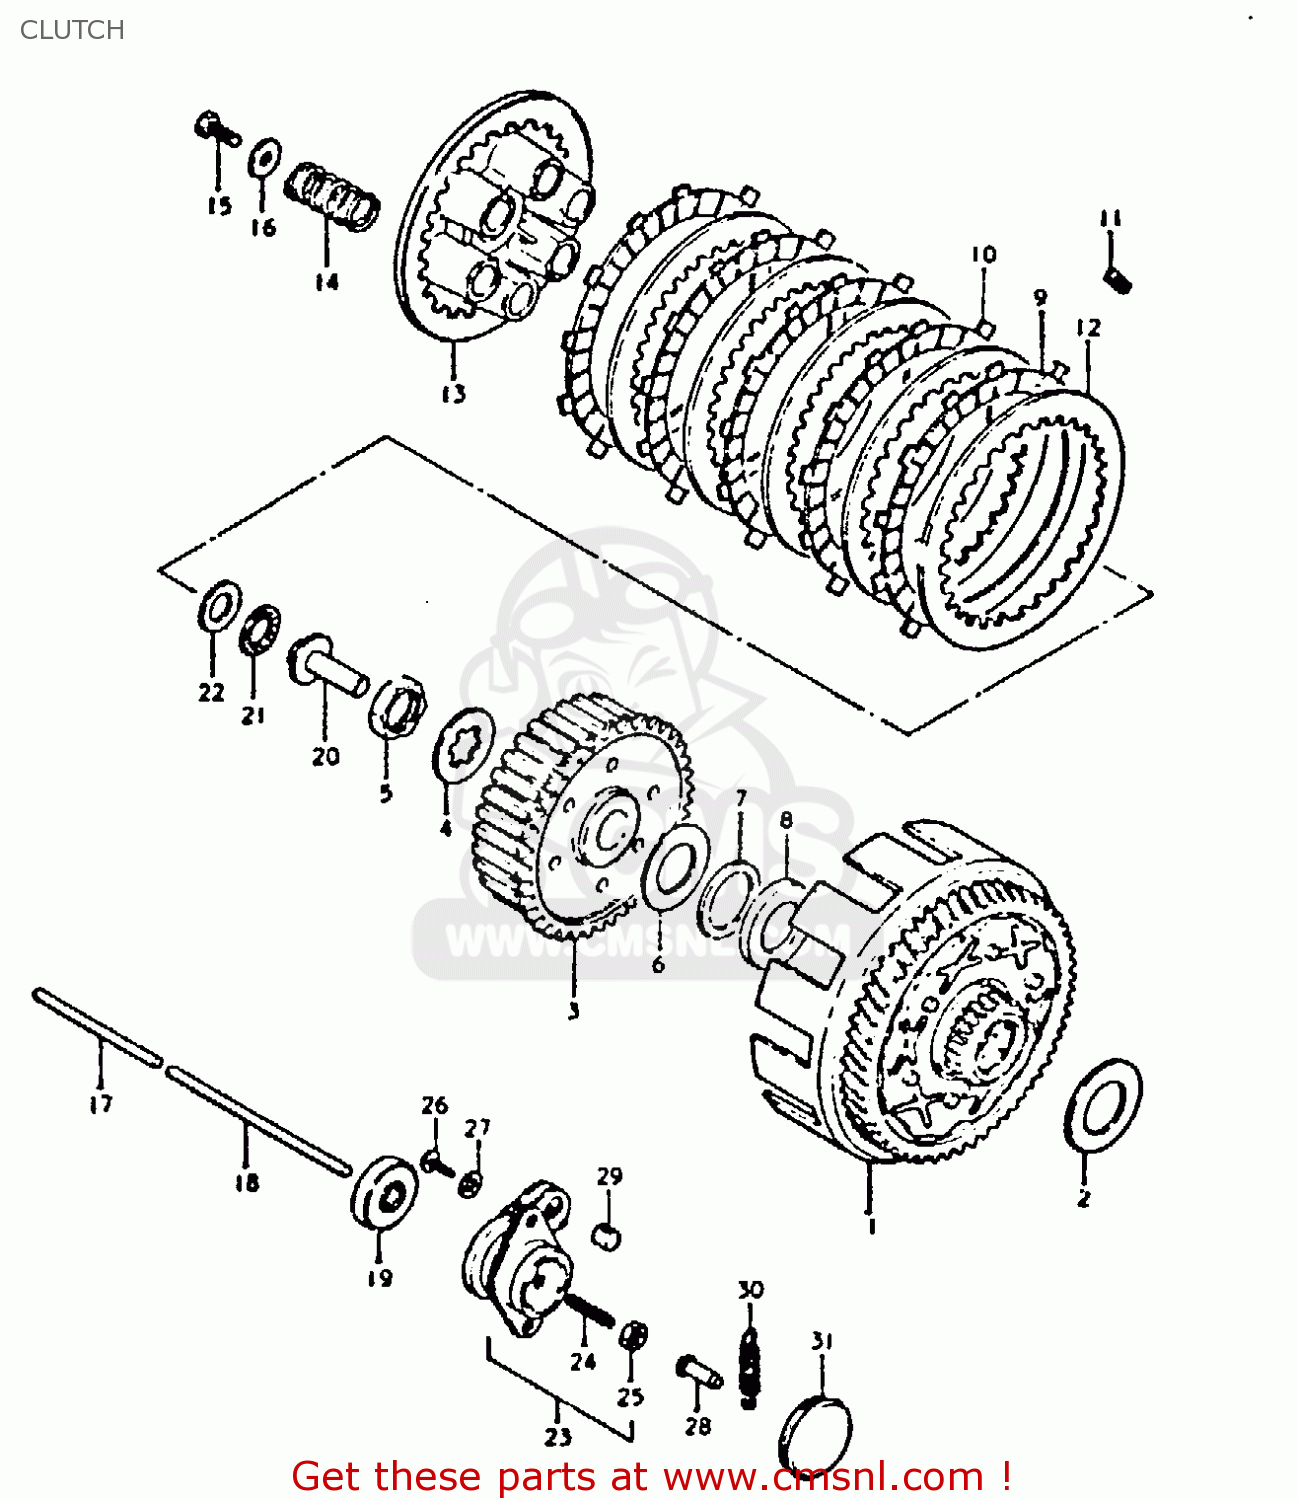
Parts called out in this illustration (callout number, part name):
1	GEAR ASSY, PRIMARY DRIVEN
2	WASHER
3	HUB,CLUTCH SLEEVE
4	WASHER,LOCK
5	NUT (20MM)
6	WASHER
7	WASHER (27X34X2)
8	WASHER
9	PLATE, DRIVE
10	PLATE,CLUTCH DRIVE (MCA)
11	DAMPER
12	PLATE,CLUTCH DRIVEN(T:2.0) (NAS)
13	DISC,CLUTCH PRESSURE
14	SPRING
15	BOLT, UPPER
16	WASHER
17	ROD,CLUTCH PUSH
18	ROD, PUSH NO. 2 (L:134)
19	SEAL,OIL(6X35X5.5)
20	PIECE,CLUTCH PUSH
21	BEARING(15X28X2)
22	WASHER
23	SCREW ASSY,CLUTCH RELEASE
24	SCREW
25	NUT 6MM
26	SCREW
27	WASHER 6MM
28	RIVET
29	PIECE,RELEASE ARM END
30	SPRING
31	CAP(OD:36)
